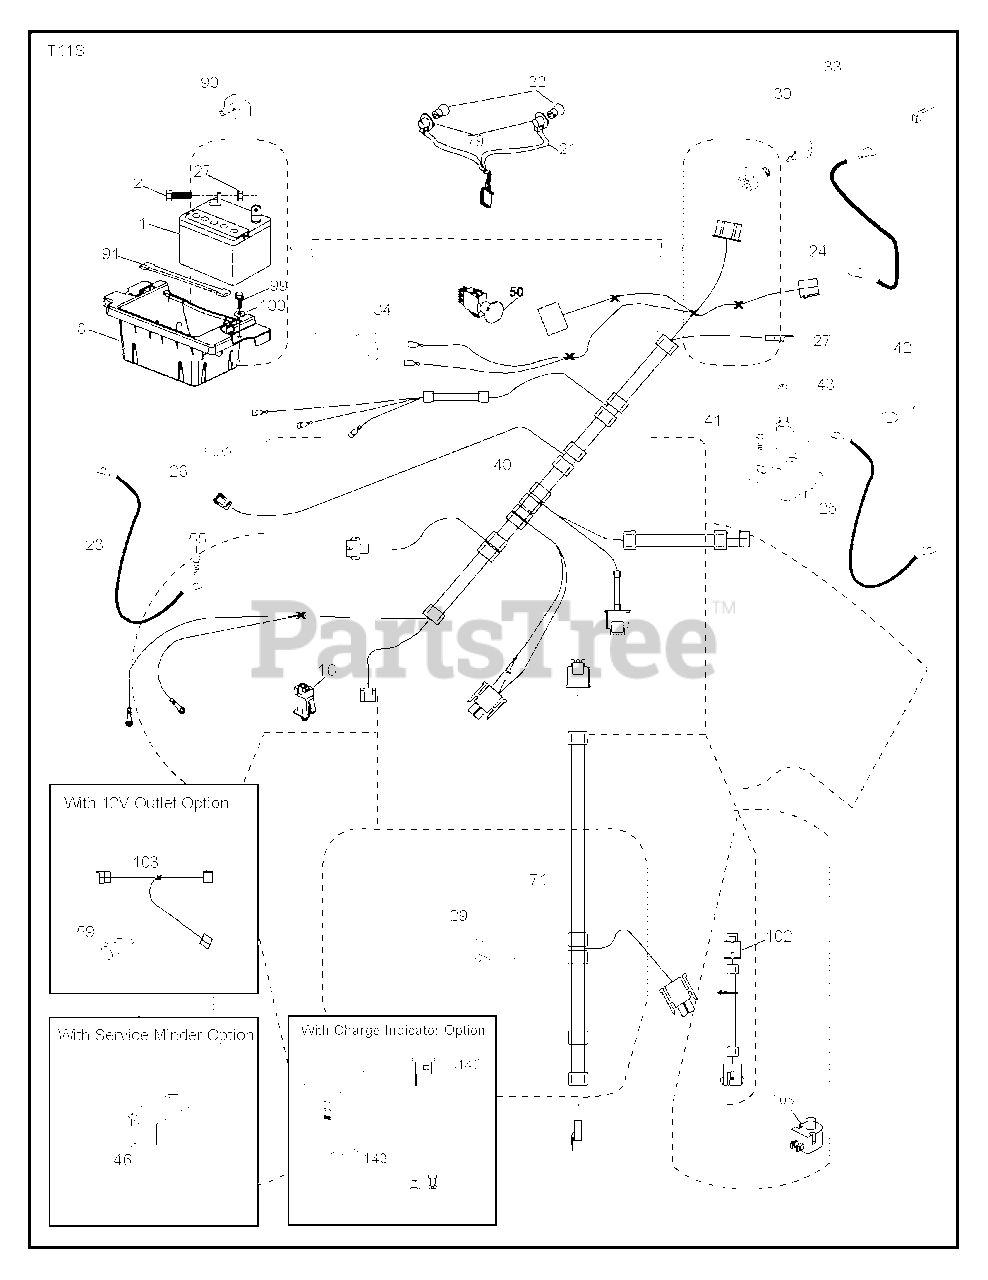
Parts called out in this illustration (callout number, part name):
1	Battery, Dry 30 Amp
2	BOLT.HEX.1/4.X.3/4.DICHROMATE
8	BOX.BATTERY.MOUNT.FRONT.LT
16	SWITCH INTERLOOK PUSH-IN
21	HARNESS.LIGHT W/4152J BULBS
24	CABLE.BATT.POS.WIRE.TG.DA SOL
25	CABLE.STARTER.8GA.17.5
26	FUSE 20AMP
27	NUT
28	CABLE GROUND 6 GA 21" 90T BLK
29	SWITCH.SEAT.DELTA.OPC.
30	SWITCH.IGN.DELTA.W.LGH.ROS
33	KEY.CHAIN.BLISTER.PACK.GEN.USA
40	HARNESS.IGN.DASH.HUQ/P
41	SCREW
42	TERMINAL COVER
43	SOLENOID.W/BRASS.PLUNGER
46	RP GUAGE.SRVCMNDR.HRMTR.
50	RB PTO.SWITCH.8 TERMINAL.BLACK
55	SCREW 5/16"
71	HARNESS-CHASSIS SUB
79	BULB HOLDER ASM.
90	COVER.TERMINAL.BATTERY
91	STRAP.BATTERY.MOUNT.FRONT(2 2)
99	SCREW HEXWSHR 1/4-20X3/4
102	HARNESS PIGTAIL PCH TEX ROS
105	REVERSE SWITCH
